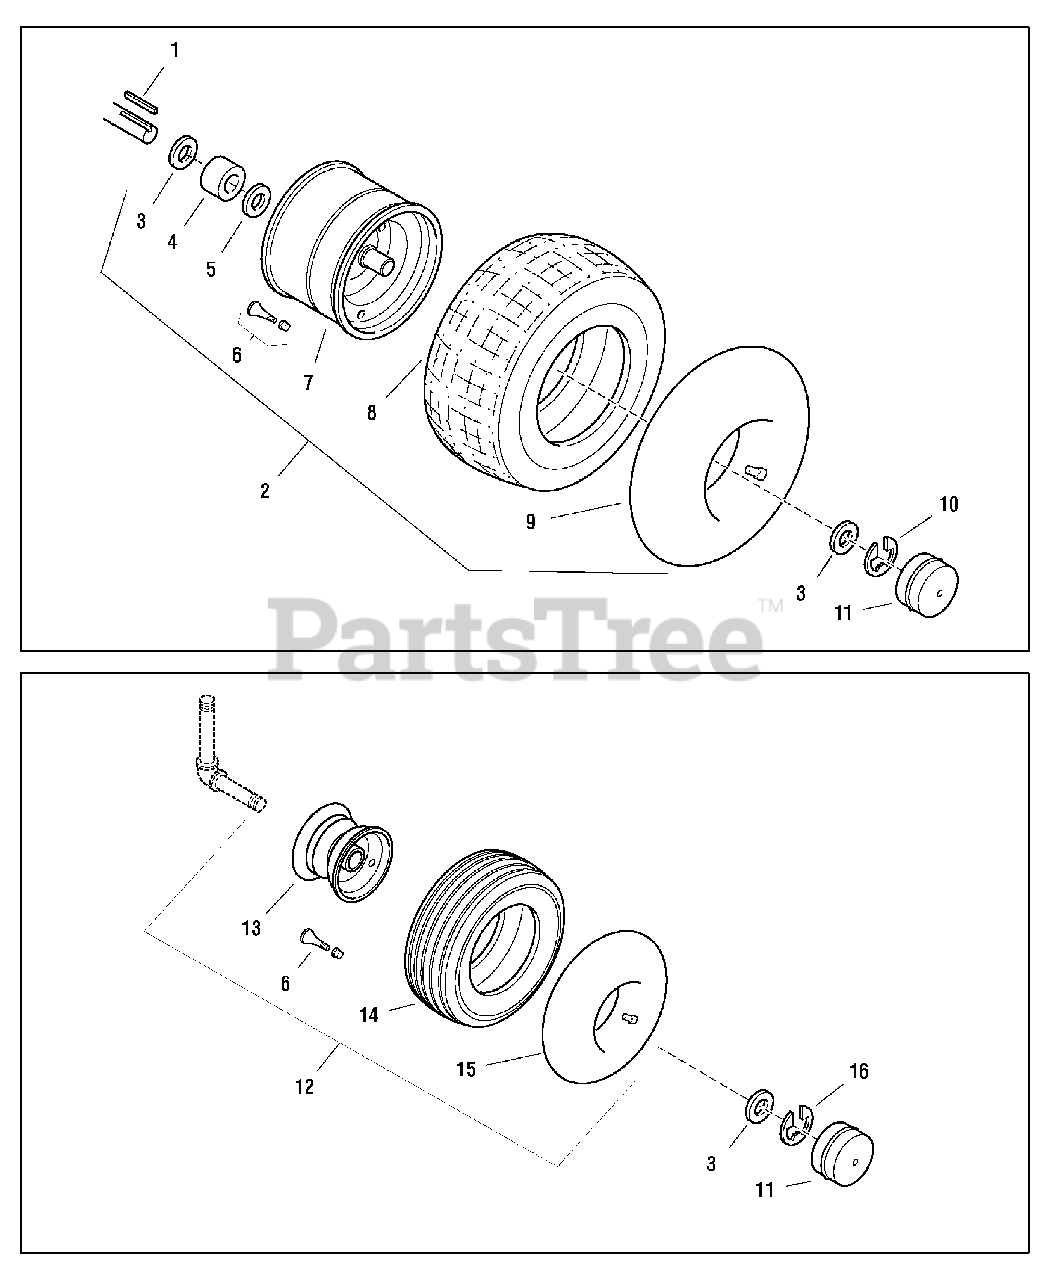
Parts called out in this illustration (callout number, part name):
1	KEY, Square, 3/16 x 3/16 x 1-1/2 long
2	REAR WHEEL & TIRE ASSEMBLY, Hoosier, (Includes Ref. Nos. 3, 4, 7 & 8)
3	WASHER, 3/4
5	WASHER
6	VALVE STEM & CAP
7	REAR WHEEL ASSEMBLY, Metallic Gray
8	TIRE, Rear Wheel, 16 X 6.50-8
9	TUBE, Rear Wheel
11	HUB CAP, Silver
12	FRONT WHEEL & TIRE ASSEMBLY, Hoosier, 13 x 5.00-6, Metallic Gray (Includes Ref. Nos. 4, 15, 18 & 19)
13	FRONT WHEEL ASSEMBLY 13 x 5.00-6, Metallic Gray (Includes Ref. No. 16)
14	TIRE, Front Wheel, 13 x 5.00-6
15	TUBE, Front Wheel, 4.10/3.50 x 6
